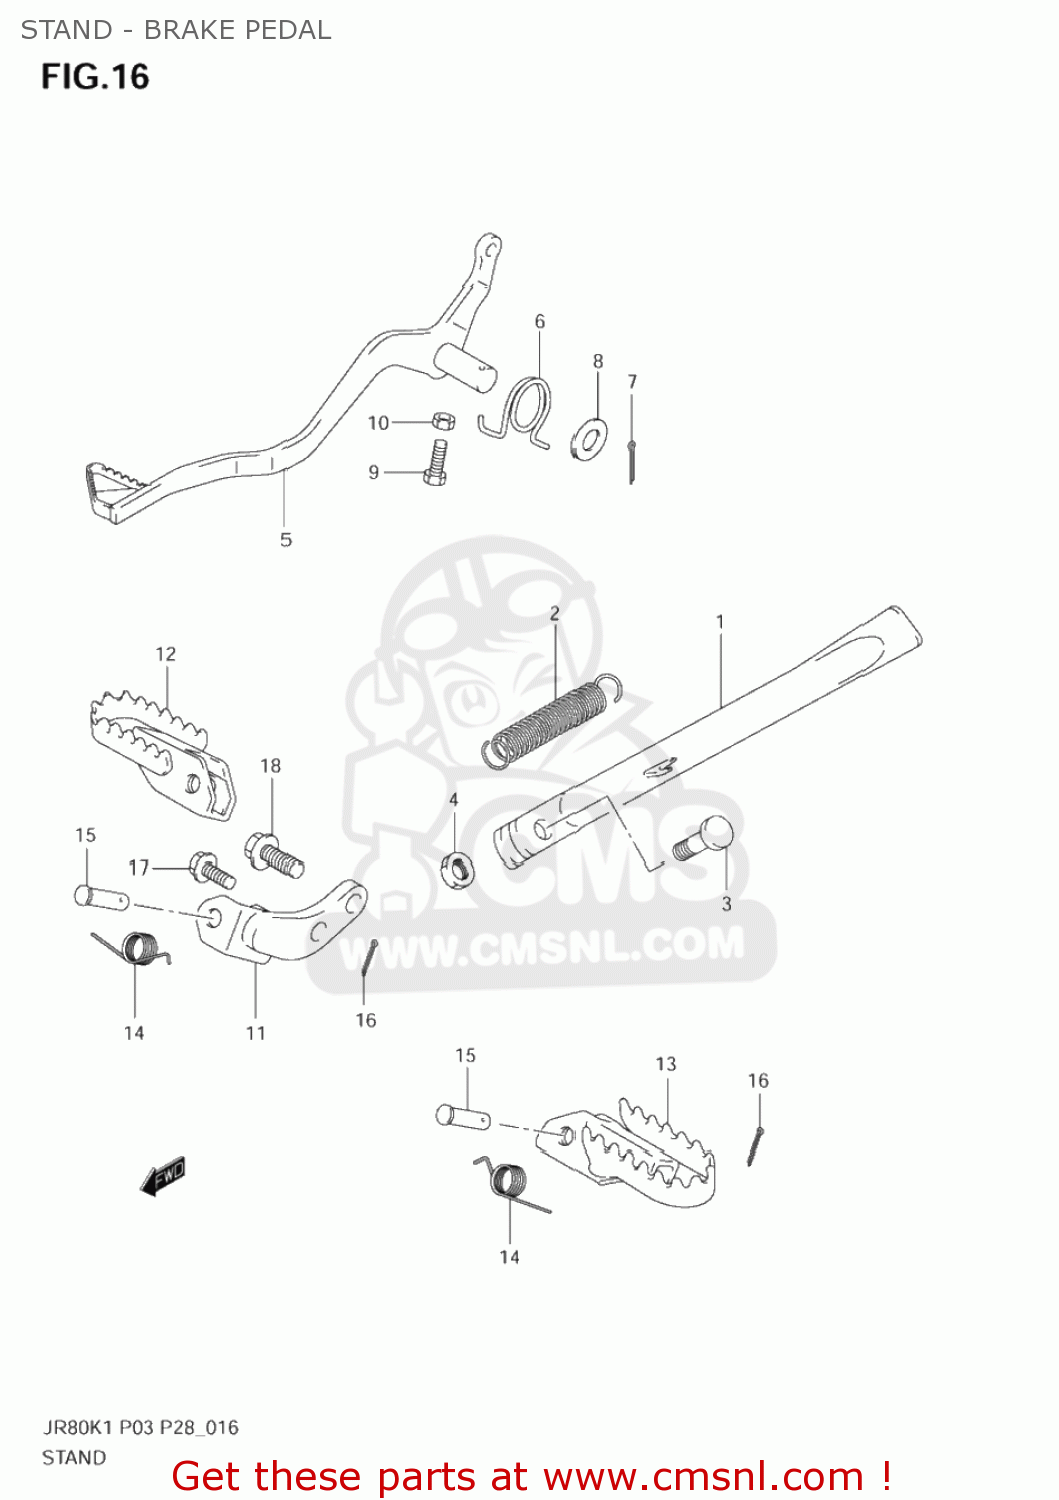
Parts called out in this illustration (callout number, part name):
1	STAND,SIDE
2	SPRING
3	BOLT(10X27)
4	NUT
5	PEDAL,BRAKE
6	SPRING
7	COTTER PIN
8	WASHER(15.5X26X2.3)
9	BOLT(6X23)
10	NUT 6MM
11	BAR,FRONT FOOTREST
12	FOOTREST,FR,R
13	FOOTREST,FR,L
14	SPRING
15	PIN
16	PIN
17	BOLT
18	BOLT(8X20)
